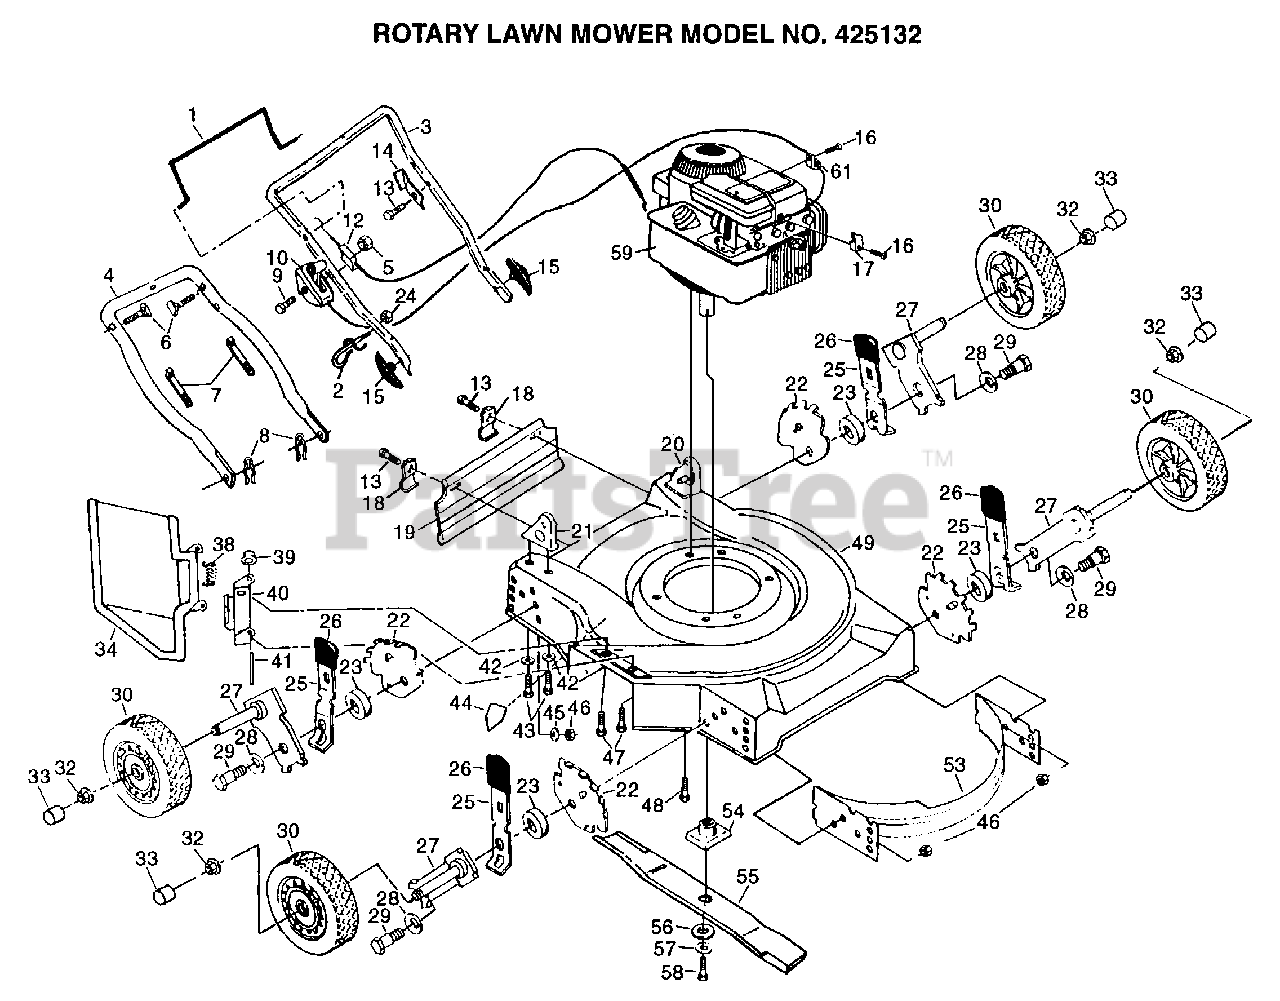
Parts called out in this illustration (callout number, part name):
1	CONTROL BAR PM
2	ROPE GUIDE
6	BOLT.HANDLE.LM
8	HAIRPIN COTTER
9	SCREW.HXHD.WASH.
10	CONTROL THROTTLE
12	"CABLE,ENG ZONE CO"
13	TAPPING SCREW
14	"BRKT,UPSTOP"
15	KNOB HANDLE
16	SCREW PM
17	CABLE CLAMP
18	"BRKT,DEFL PM"
19	SKIRT.REAR.FGD.22
22	BRACKET.ADJ.9POS.
24	NUT
25	SPRING SELECTOR
26	KNOB PM
27	ARM.AXLE.ASM.BZP.
28	"WASHER, BELLEVIL."
29	BOLT SHLD 3/8-16
30	WHEEL.ASM
32	HEX FLANGE LOCKNT
33	HUB CAP-PLASTIC
38	"SPRING,TORSION"
39	PUSH ON SPEED NUT
40	"BRKT,HSG"
41	"ROD,HINGE "
42	STEEL WASHER
43	SCREW
44	DECAL-DANGER PM
46	LOCKNUT PM
47	SCREW
48	SCREW
49	KIT.HSG.22SD PUSH
53	BAFFLE.FRT/REAR
54	BLADE ADAPTOR
55	"BLADE.MULCH.22"""
56	"WASHER,HARDEN"
57	LOCKWASHER
58	SCREW
61	GUIDE CLIP PM
